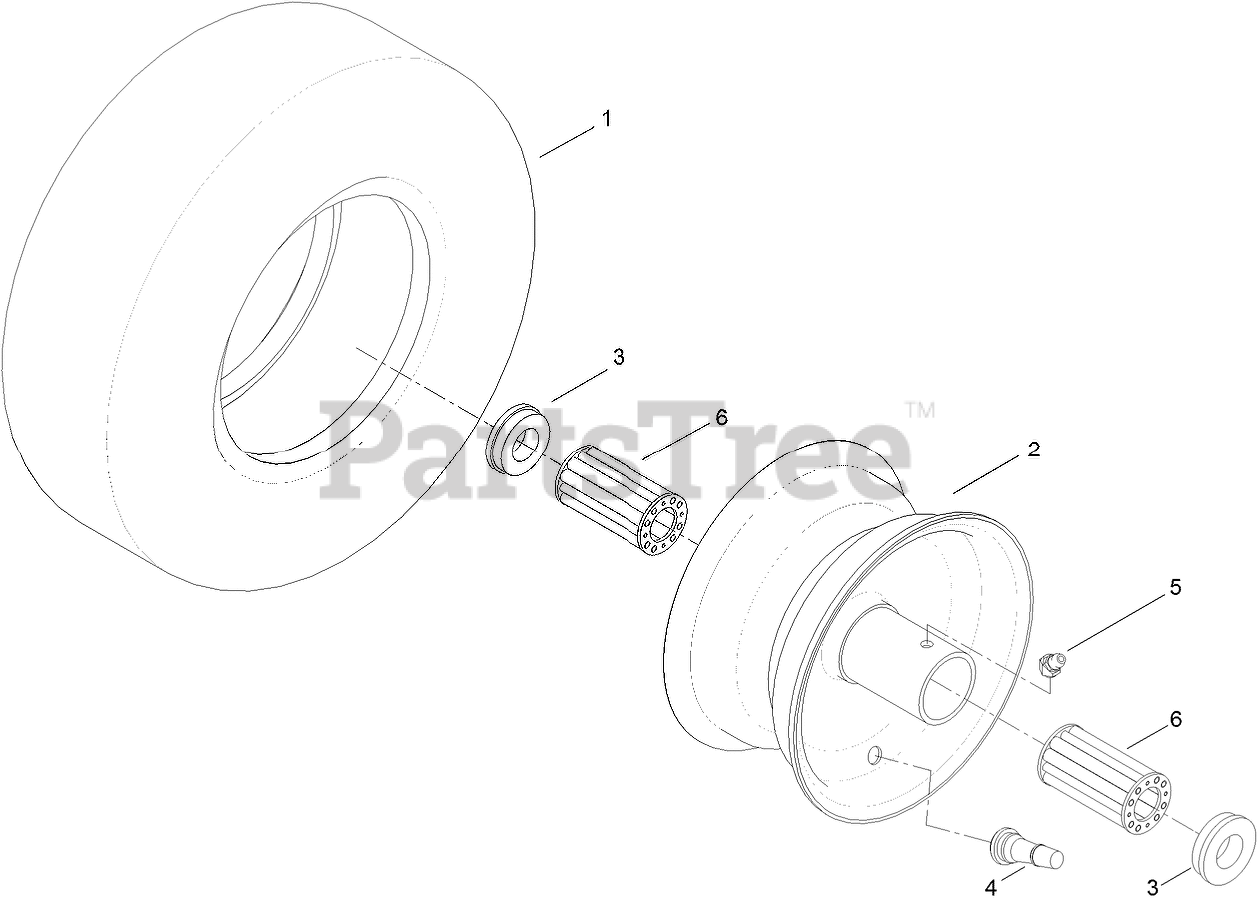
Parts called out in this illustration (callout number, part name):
2	RIM-6 INCH
3	BUSHING-FLANGE
4	VALVE
5	FITTING-ZERK
6	BEARING
